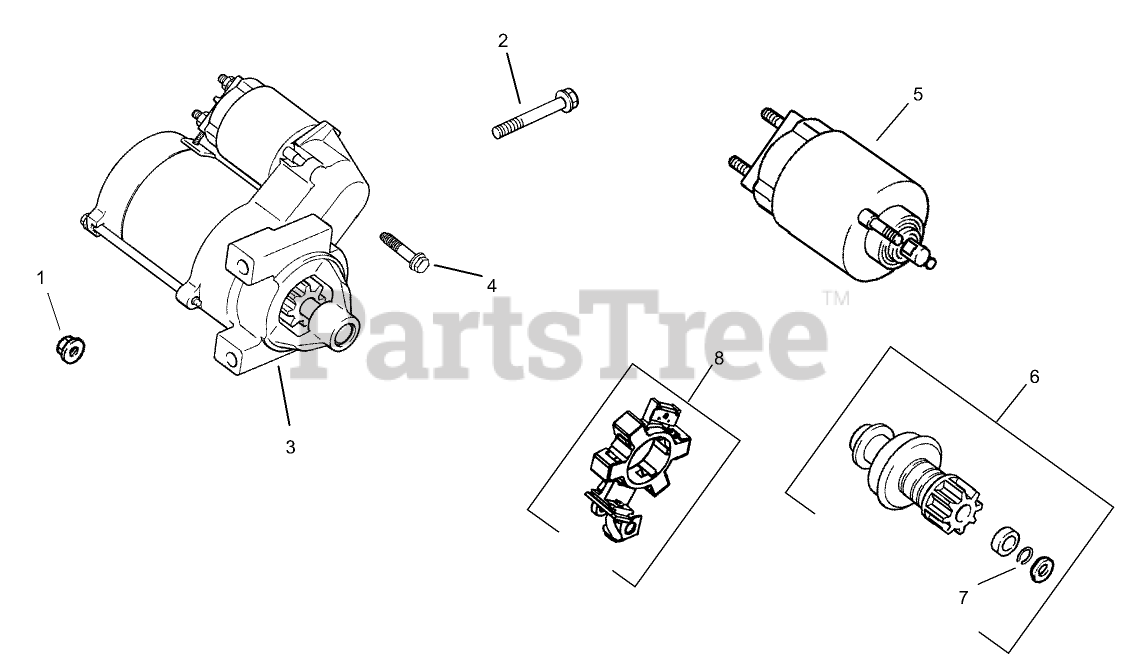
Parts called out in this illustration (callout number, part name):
1	NUT-FLANGE (M8X1.25)
2	SCREW-FLG (M8X1.25X80)
3	Starter ASM (Includes 4-8)
4	Screw-External Torx Head
5	Solenoid Kit (Includes 4)
6	Pinion Drive Kit (Includes 7)
7	RING-RETAINING
8	BRUSH HOLDER KIT
